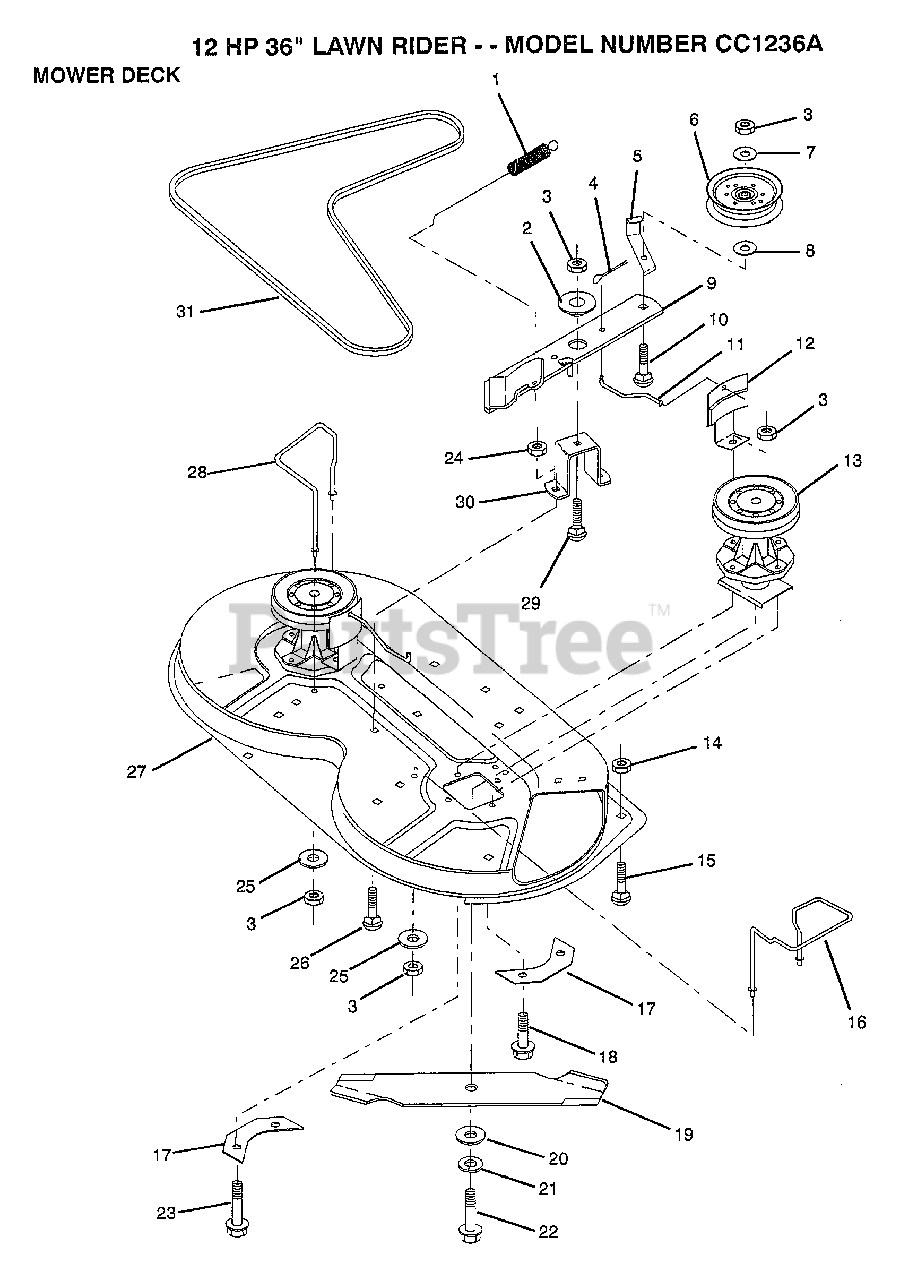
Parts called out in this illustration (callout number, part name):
2	SPACER RETAINER
6	PULLEY IDLER
7	WASHER
8	WASHER GT
10	BOLT CARRIAGE
11	ROD BRAKE
12	BRAKE LT
13	MANDREL ASS'Y
15	BOLT
16	"GUIDE,BELT RH"
17	SUPPORT PLATE LT
18	SCREW
19	"BLADE.36""HIGH LIF"
20	WASHER
22	BOLT.3/8-24X1-1/2
23	SCREW
25	WASHER
26	BOLT
28	GUIDE BELT LH
29	BOLT D
30	"SUPT,IDLER ARM"
31	BELT.MOWER.79.75
